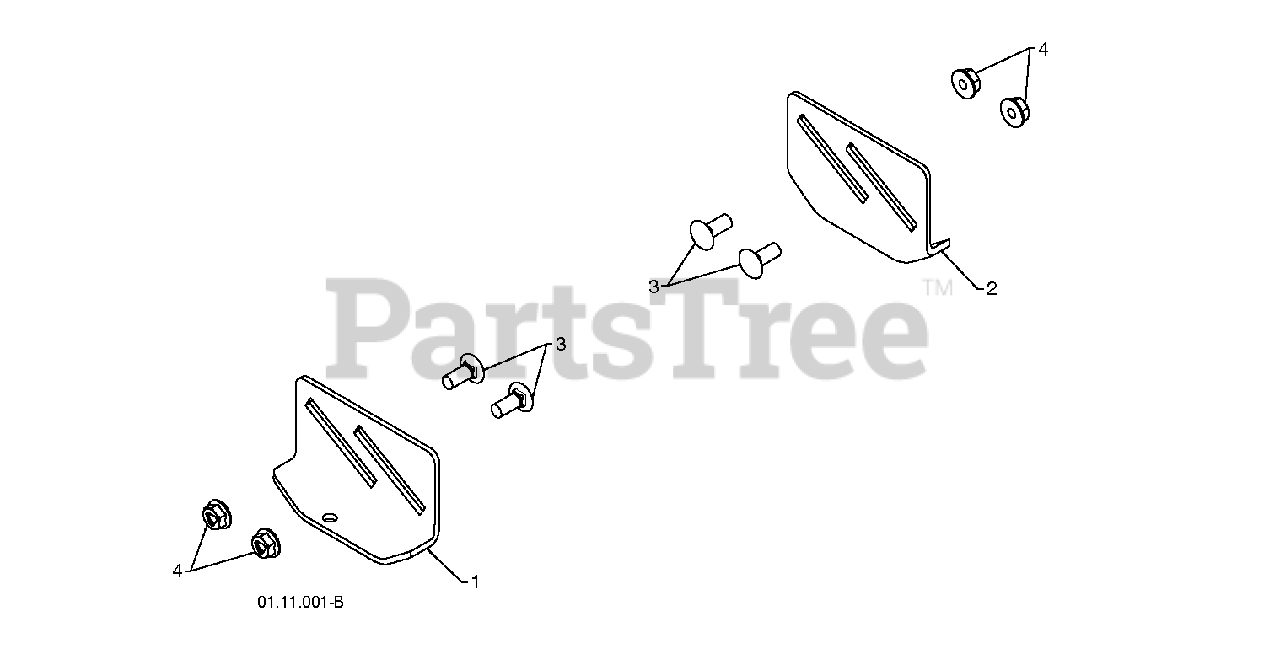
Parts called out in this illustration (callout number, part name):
1	RP PLATE.SKID.LH.PNT
2	PLATE.SKID.ADJ.RH.BLACK
4	NUT, LOCK 5/16-18
